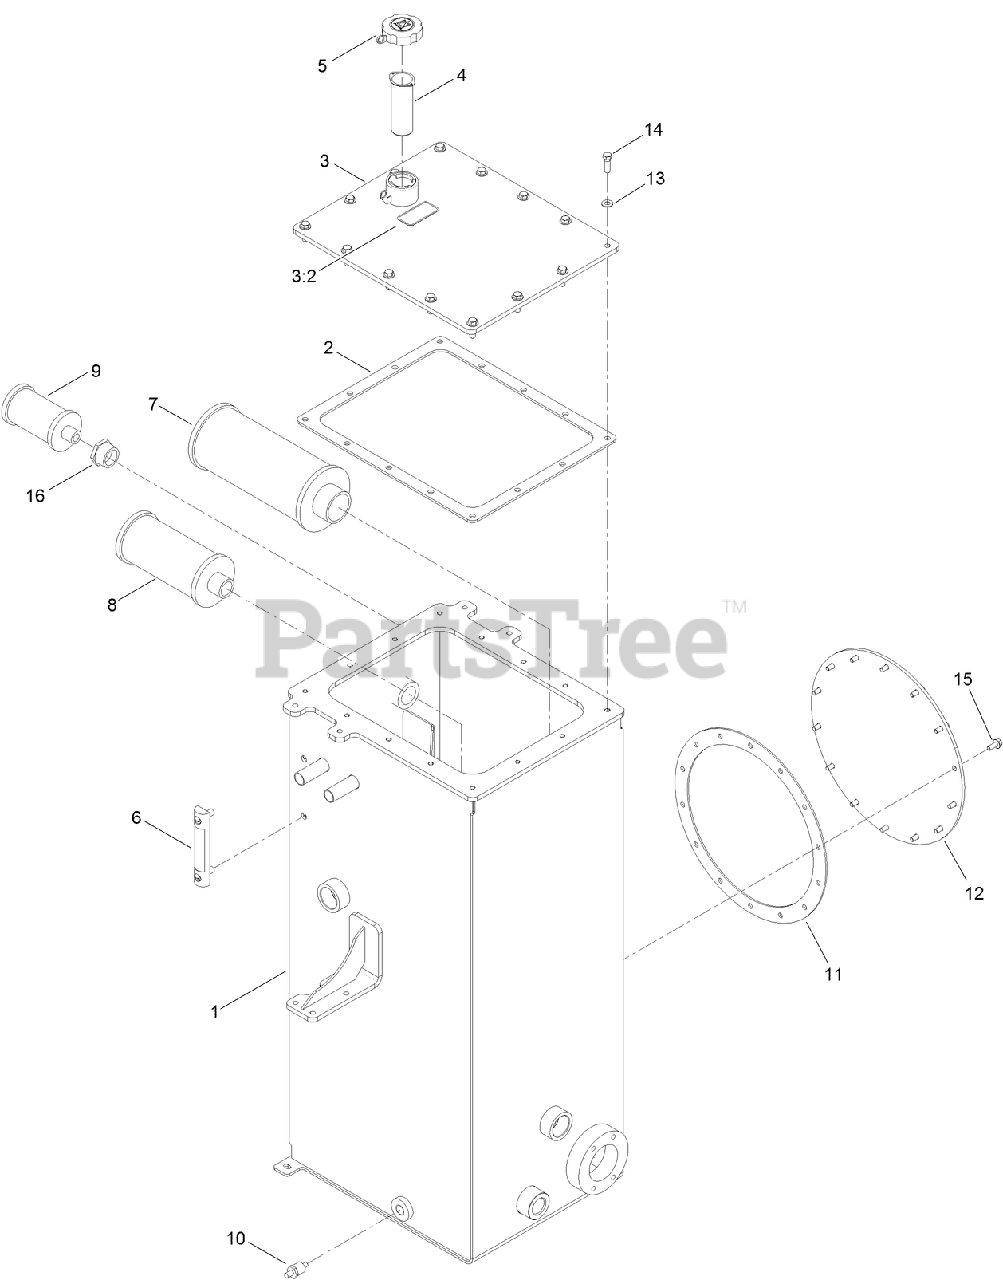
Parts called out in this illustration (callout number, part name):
1	TANK-HYD
2	GASKET-COVER
3	HYD TANK COVER ASM
3:2	DECAL-HYD FLUID
4	FILTER-SCREEN, MESH
5	CAP-HYD FLUID (W/ LOCK)
6	GAUGE-SIGHT
7	STRAINER-NIPPLE
8	STRAINER-SUCTION
9	STRAINER-NIPPLE
10	SENDER-TEMPERATURE, WATER
11	GASKET-HYD, TANK
12	COVER-HYD, TANK
13	WASHER-PLAIN
14	SCREW-HH
15	SCREW-HHF
16	FITTING-REDUCER
